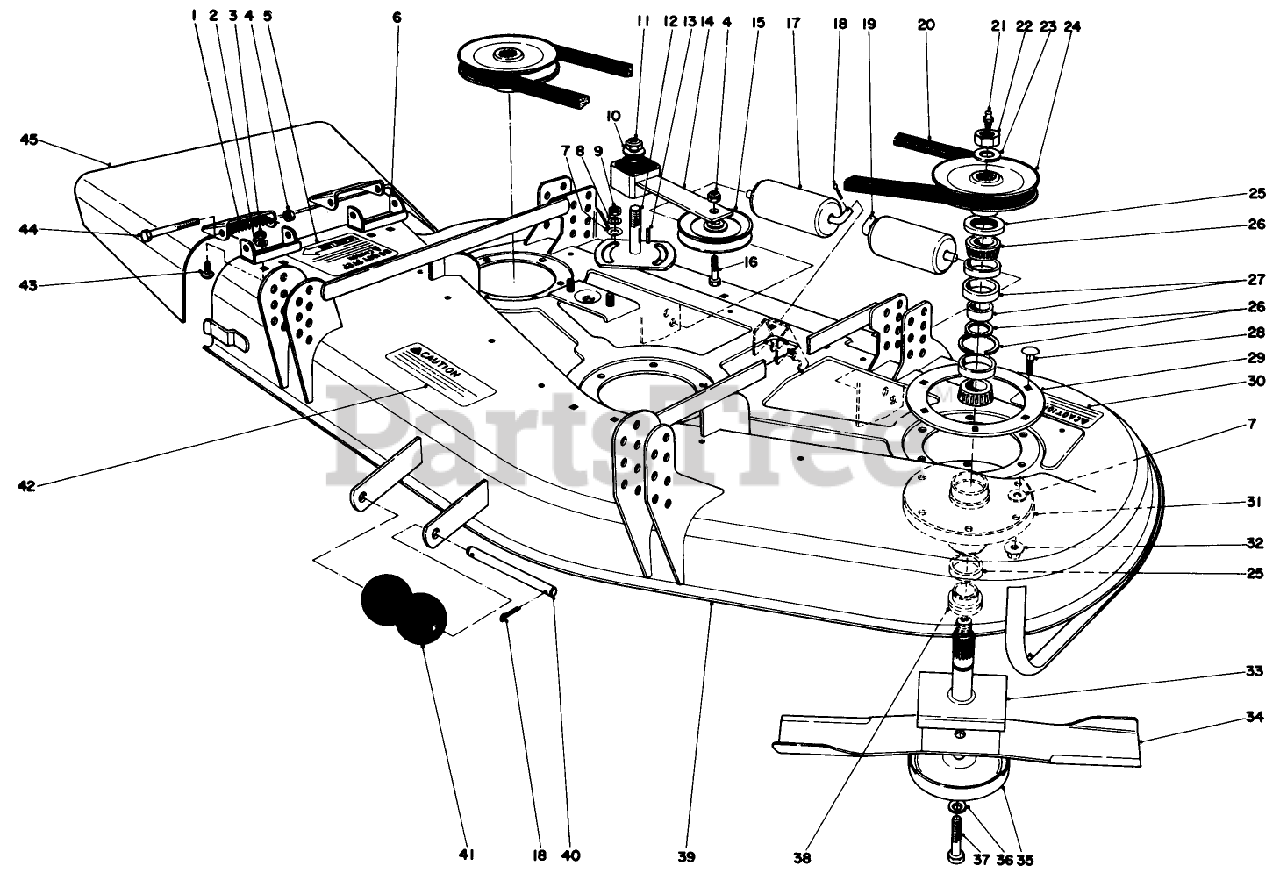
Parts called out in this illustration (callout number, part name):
1	SPRING
2	SCREW-HH
3	NUT-HEX
4	NUT-HEX
7	WASHER-FLAT
8	WASHER-LOCK
9	NUT-JAM
10	WASHER-FLAT
11	NUT-LOCK, NI
12	PLATE-IDLER
13	KEY-SQUARE
17	ROLLER-DECK
18	PIN-COTTER
19	SHAFT-ROLLER, REAR
20	V-BELT
21	FITTING-GREASE
22	NUT-HEX
23	WASHER
25	SEAL-OIL
26	BEARING ASM
27	SPACER-SET, MATCHED
28	SCREW-CARR
30	CAUTION DECAL (BLADE)
32	NUT-HF
33	SHAFT
36	WASHER-LOCK
37	SCREW-BLADE
38	SPACER
40	SHAFT-ROLLER
41	ROLLER
44	SCREW-HH
